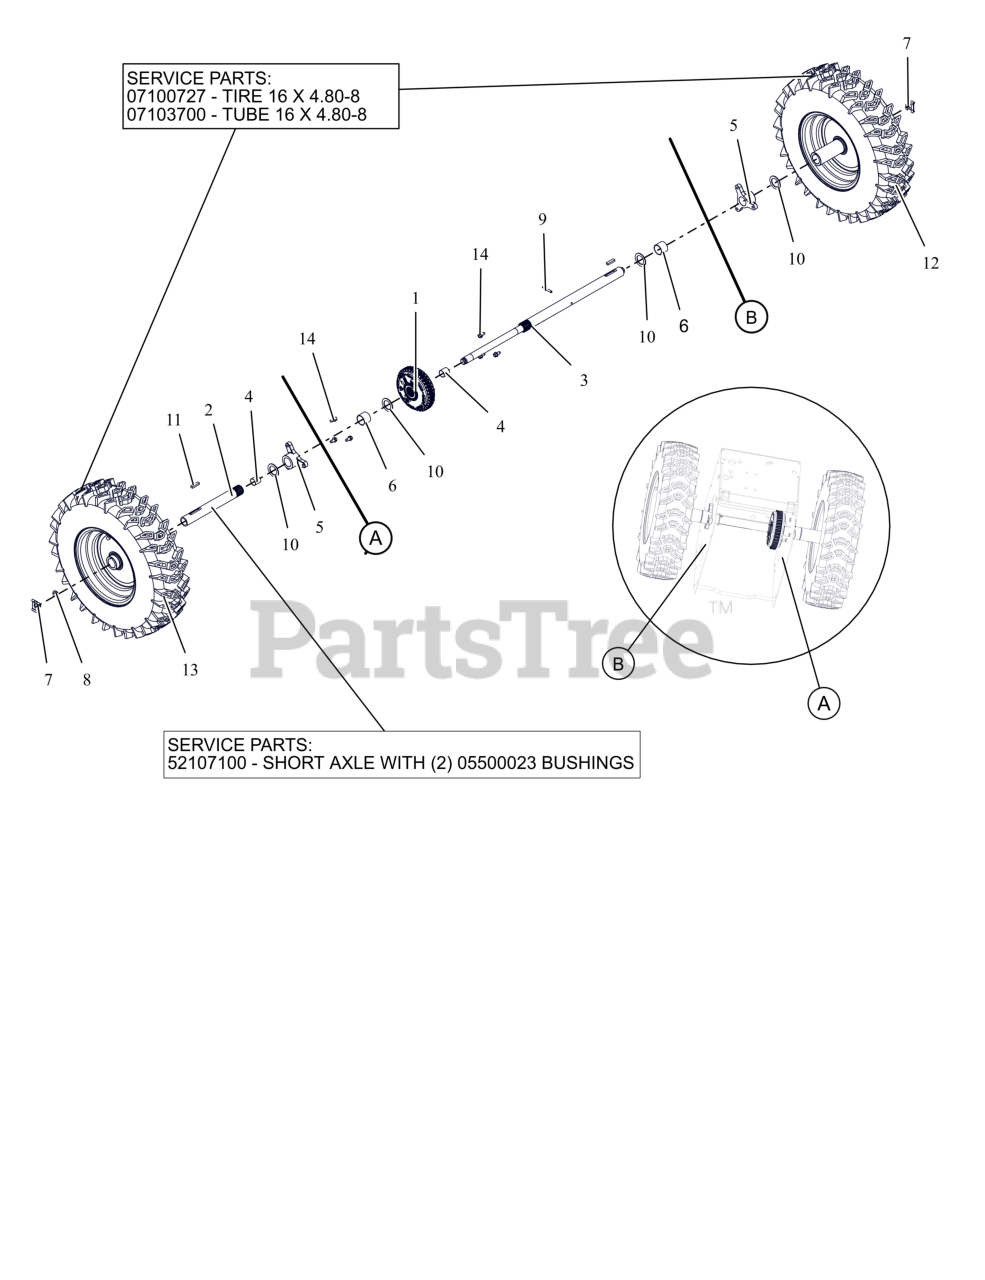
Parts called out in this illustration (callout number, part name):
1	DIFFERENTIAL, AUTOMATIC
2	KIT, SHORT AXLE W/BUSHINGS
3	AXLE, LONG - DIFFERENTIAL
4	BSHG-SLV .706X.764X.75 BRZ
5	BUSHING, AXLE
6	BSHG-SLV, 1.012X1.125X.875
7	CLIP, SNAP .625 DIA
8	RG-RTNG-EXT .625X.042
9	PIN-ROLL .188X1.25
10	WSHR, FLT 1.010X1.505X.062 ZCC
11	KEY-RECT .25X.188X1.00
12	TIRE/WHEEL LH 16X4.8-8 DIFF T2
13	TIRE/WHEEL RH 16X4.8-8 DIFF T2
14	SCR-TAP .25-20X.50 HWH ZCC
